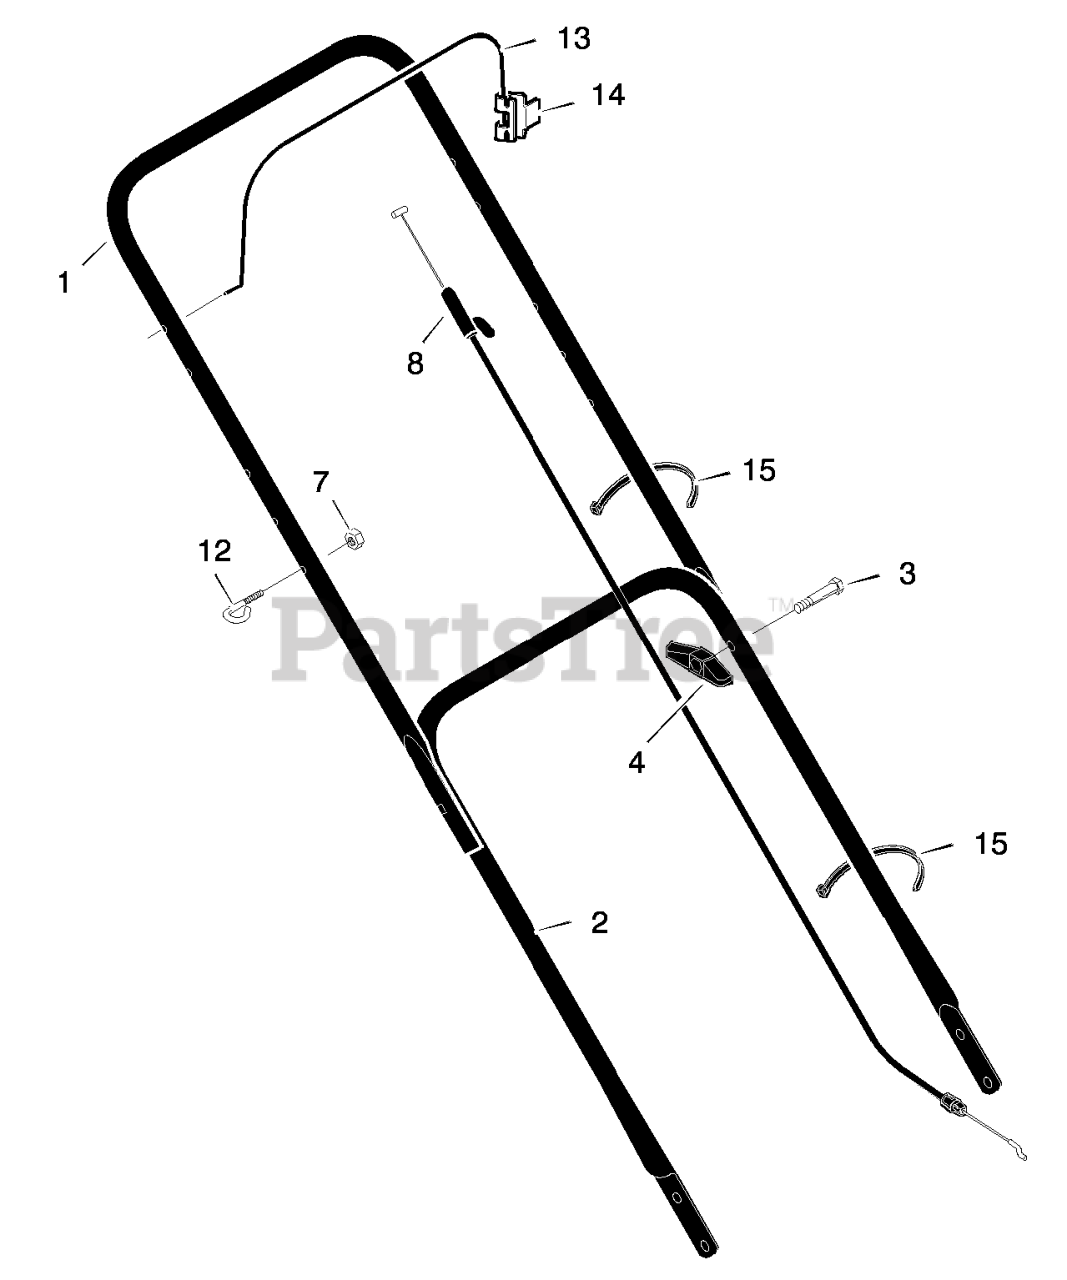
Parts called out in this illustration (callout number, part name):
1	Handle, Upper (Black)
2	Handle, Lower (Black)
4	Knob, Plastic
7	Locknut
8	Engine Stop Cable
12	Guide, Rope
13	Engine Stop Lever
14	Bracket, Stop Lever
15	Fastener, Cable
